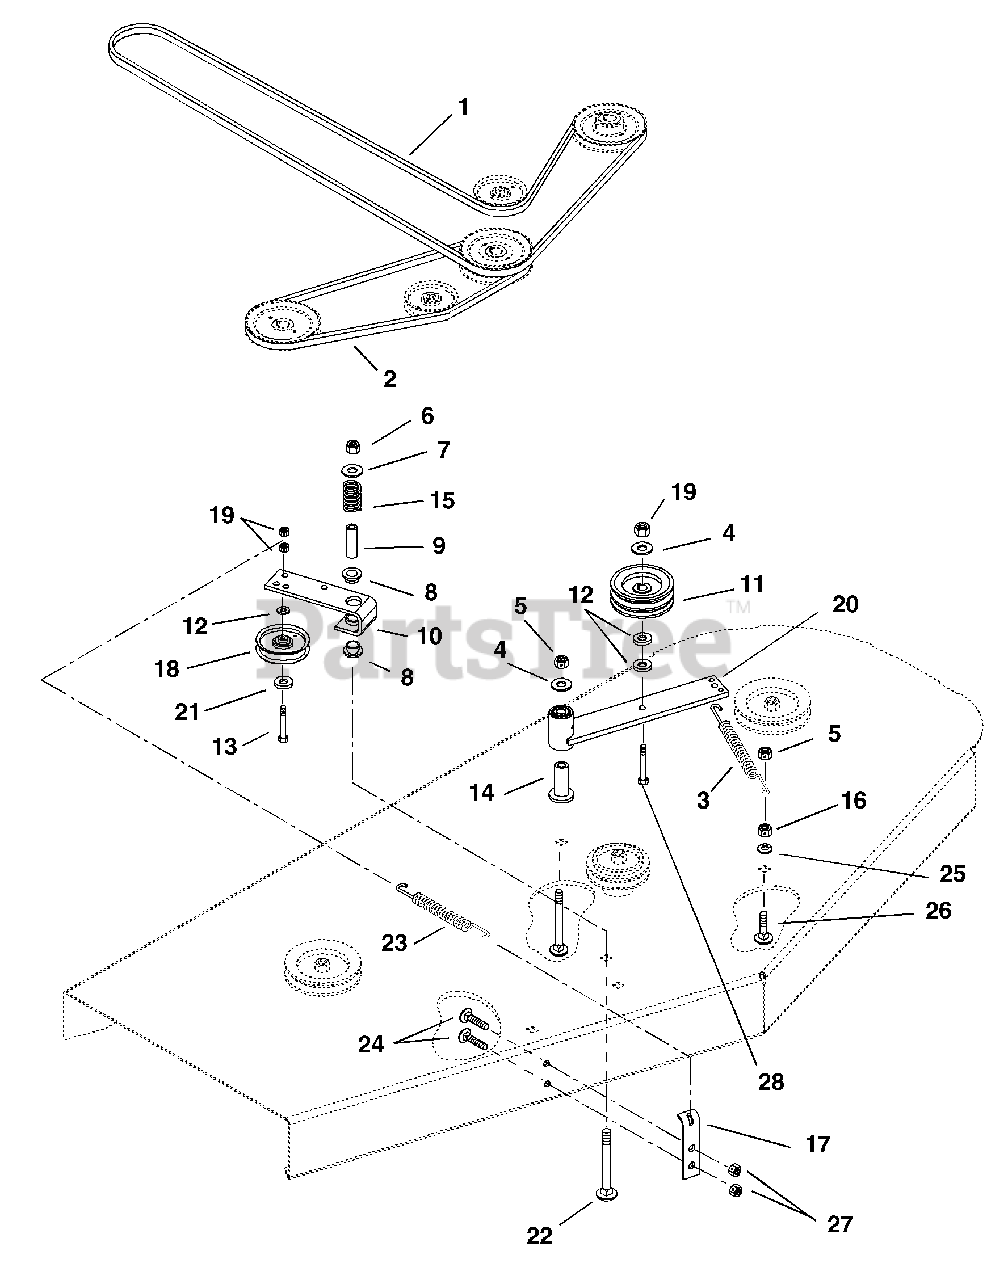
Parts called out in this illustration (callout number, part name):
1	V-Belt B-Section 60" Mower
1	V-Belt B-Section 50" Mower
2	V-Belt A-Section 60" Mower
2	V-Belt A-Section 50" Mower
3	Spring, Coil
4	Washer-Flat-Steel .406 x .812 x .065
5	Nut-Locking .38-16
6	Nut-Locking .50-13
7	Washer-Flat-Steel .531 x 1.250 x .100
8	Bushing-Flange .762 x 1.0 x .580 x 1.48
9	Spacer .560 x .750 x 2.437
10	Arm, Idler Pivot
11	Idler-Flat 4 x .38 (2.00 W)
12	Bushing .406 x .750 x .188
13	Bolt-Hex .38-16 x 2.00 Grade 5
14	Bearing, Pedestal
15	Spring-Compression .085 x .80 x 1.00
16	Nut-Hex .38-16
17	Anchor, Spring
18	Sheave, Idler
19	Nut-Locking-Ctr .38-16
20	Assembly, Idler Pivot Arm
21	Washer-Flat-Steel .375 x 1.125 x .065
22	Bolt-Round Head Square Neck .50-16 x 3.50
23	Spring, Ext.
24	Bolt-Round Head Square Neck .31-18 x .75 Gr. 5
25	Washer-Locking .38 x .875 x .160
26	Bolt-Round Head Square Neck .38-16 x 1.75
27	Nut-Locking-Ctr .31-18
28	Bolt-Hex .38-16 x 2.25 Grade 5
